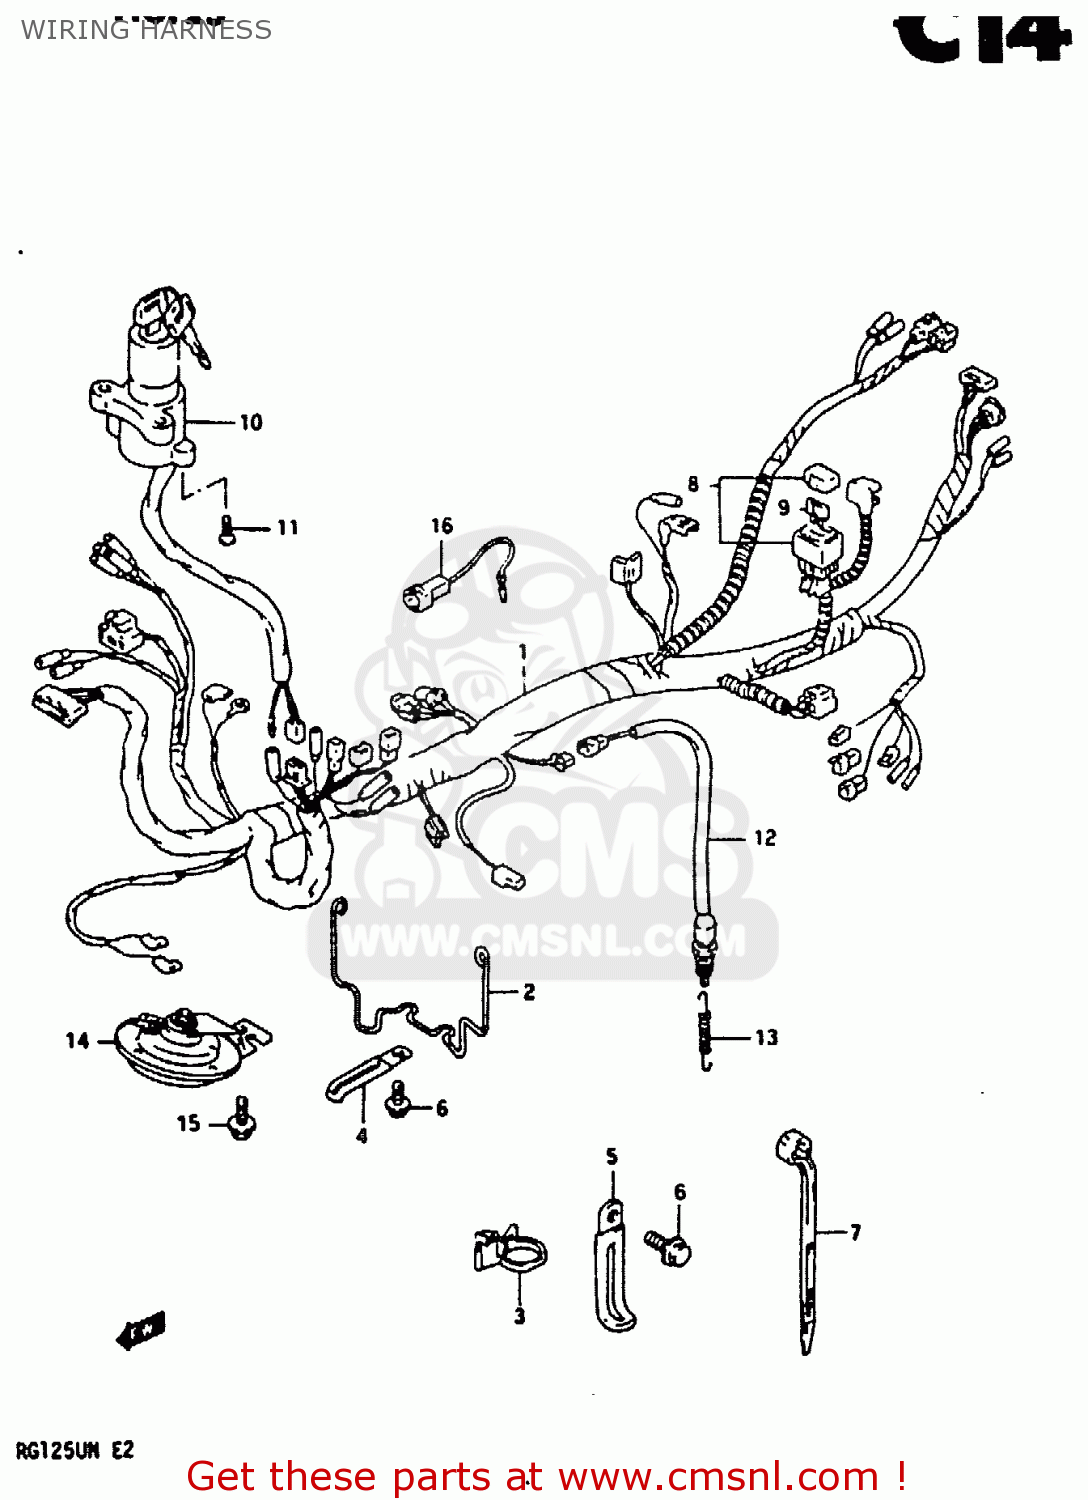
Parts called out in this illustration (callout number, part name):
1	HARNESS, WIRING
2	GUIDE, HARNESS
3	CLAMP(L:90)
4	CLAMP
5	CLAMP
6	BOLT
7	CLAMP(L:95)
8	BOX ASSY,FUSE
9	FUSE(15A)
10	LOCK ASSY, STEERING
11	SCREW(6X18)
12	SWITCH ASSY,STOP LAMP
13	SPRING
14	HORN ASSY
15	BOLT 6X12
16	WIRE, NEUTRAL SWITCH LEAD
